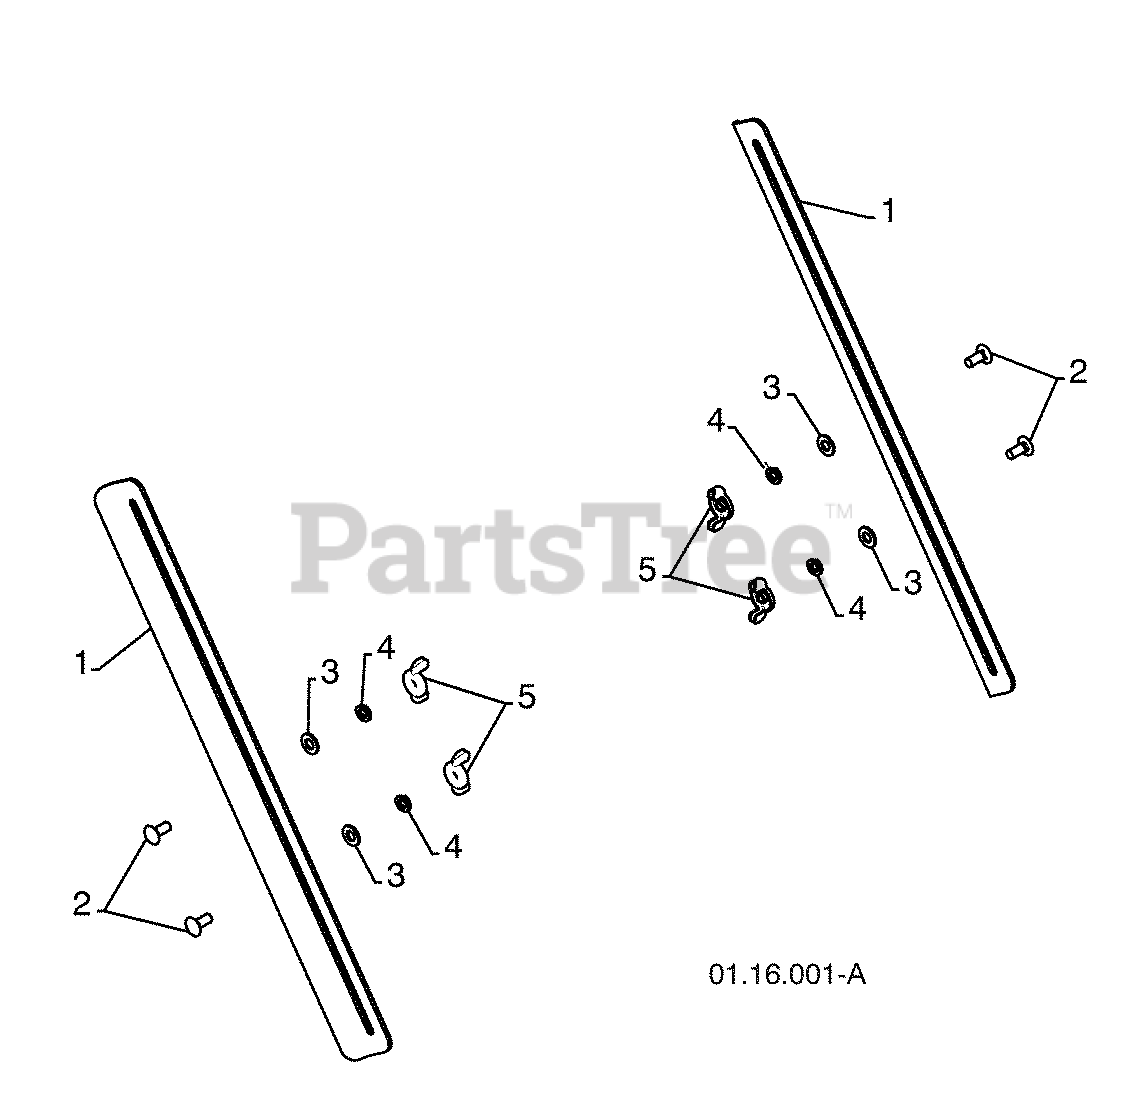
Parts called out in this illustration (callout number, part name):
1	DRIFT CUTTER BAR
2	CARRIAGE BOLT 5/16-18 X .750
3	PLASTIC WASHER
4	LOCKWASHER 5/16
5	NUT 5/16-18
